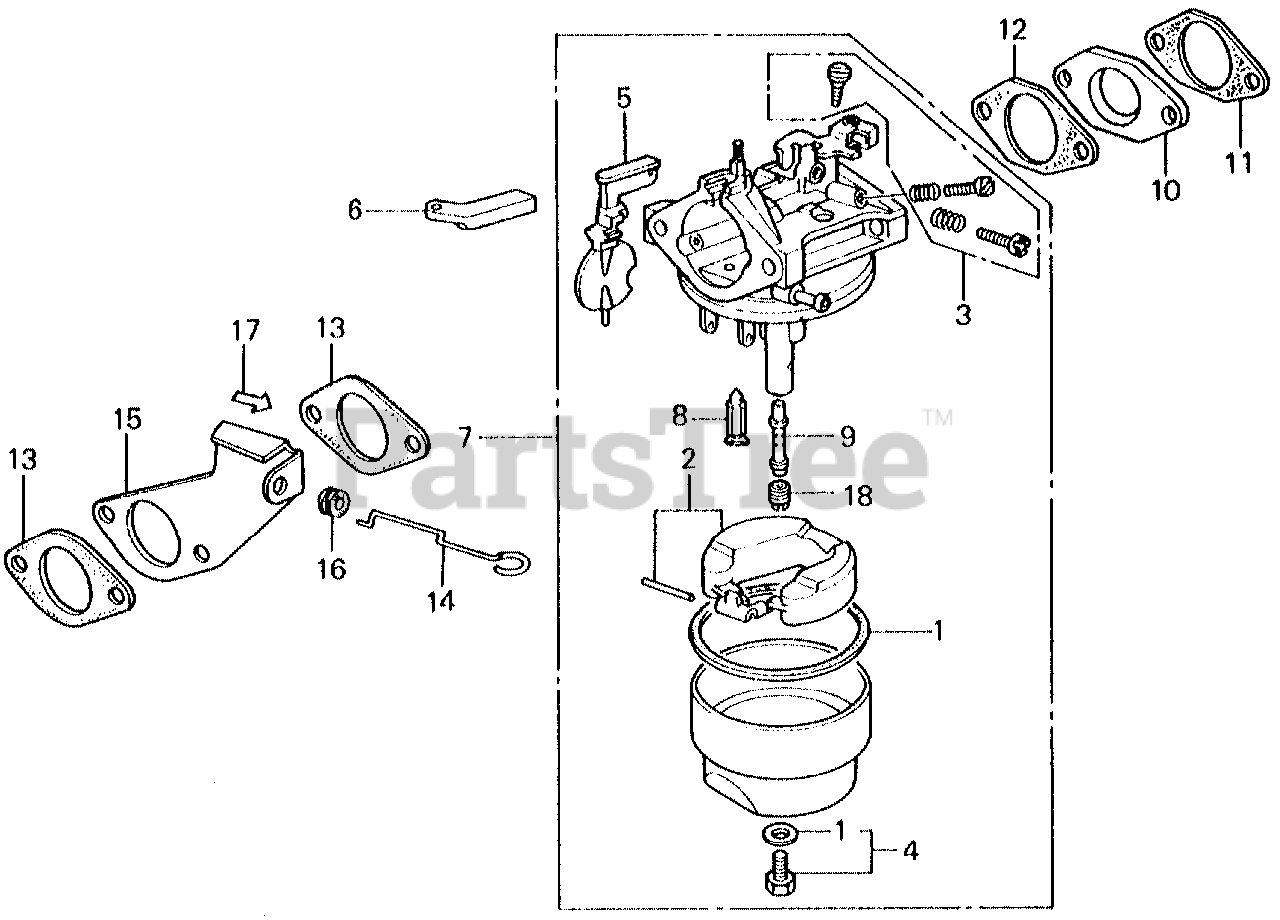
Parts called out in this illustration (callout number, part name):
1	GASKET SET
2	FLOAT SET
3	SCREW SET A
4	SCREW SET B
5	CHOKE SET
6	ARM, CHOKE LEVER
7	CARBURETOR ASSY.
7	CARBURETOR ASSY. (BB30C A)
8	VALVE, FLOAT
9	NOZZLE, MAIN
10	INSULATOR, CARBURETOR
11	GASKET, INSULATOR
12	GASKET, CARBURETOR
13	GASKET, AIR CLEANER
14	ROD, CHOKE CONTROL
15	STAY, CHOKE CONTROL
16	GROMMET, CHOKE ROD
17	MARK, CHOKE
18	JET, MAIN (#65) Use from Engine SN BB30C A.
18	JET, MAIN (#68) Use from Engine SN BB30C A.
18	JET, MAIN (#70) Use from Engine SN BB30C A.
18	JET, MAIN (#72)
